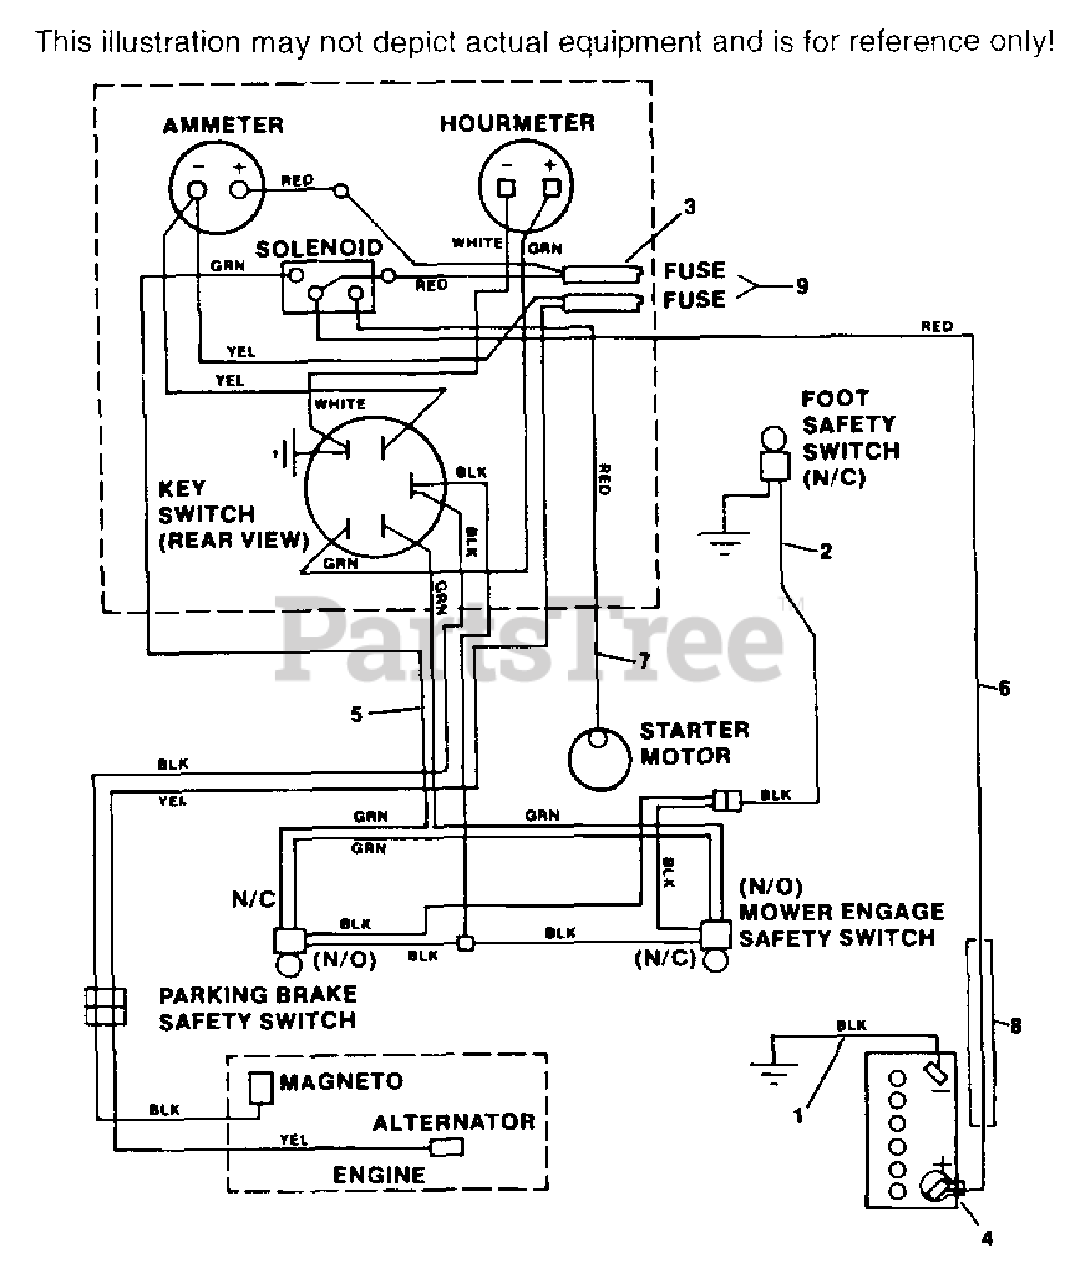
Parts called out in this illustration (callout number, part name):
1	BATTERY CABLE GROUND
2	WIRE HARNESS, FOOT SAFETY SWITCH
3	WIRE HARNESS, SOLENOID TO AMMETER
4	RUBBER BOOT
5	WIRE HARNESS
6	BATTERY CABLE
7	BATTERY CABLE
9	FUSE, 20 AMP BLADE TYPE AUTOMOTIVE
